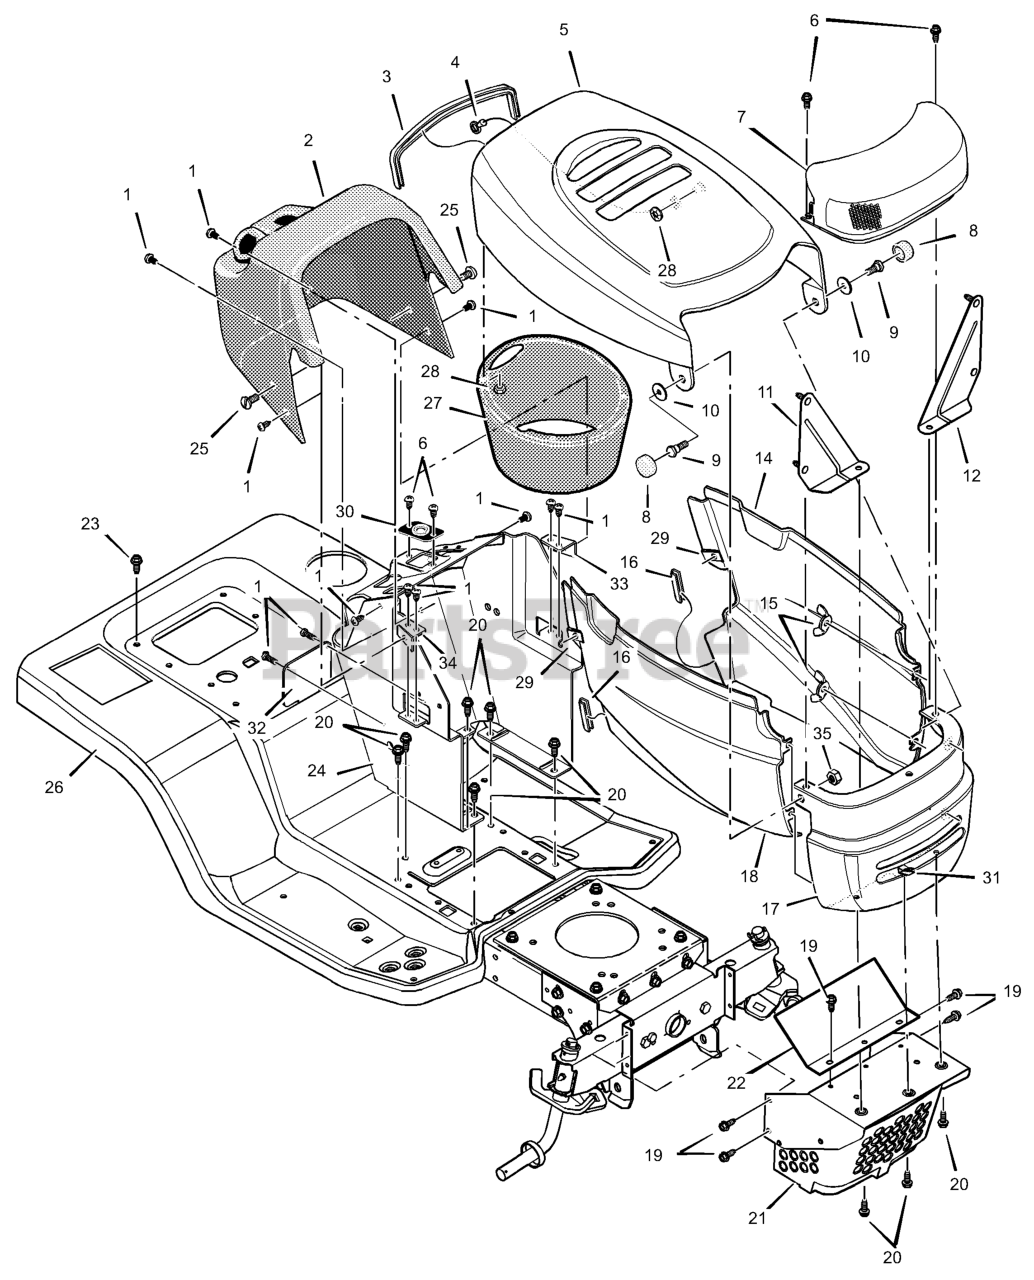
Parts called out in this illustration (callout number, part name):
1	Screw
3	Trim 2.23"
5	Hood Assembly
7	Lens & Reflector Assembly
8	Cap, Pivot
9	Bolt, Shoulder
10	Base, Pivot
11	Brace, Right Grille Assembly
12	Brace, Left Grille Assembly
14	Panel, Left Side
15	Wingnut
16	Trim 0.39"
18	Panel, Right Side
21	Guard Assembly, Muffler
22	Shield, Upper Heat
26	Deck Seat
28	Retainer, Push
29	Cap, Push
30	Bearing, Steering
32	Panel, Access
33	Bracket, Right Console
34	Bracket, Left Console
35	Nut
